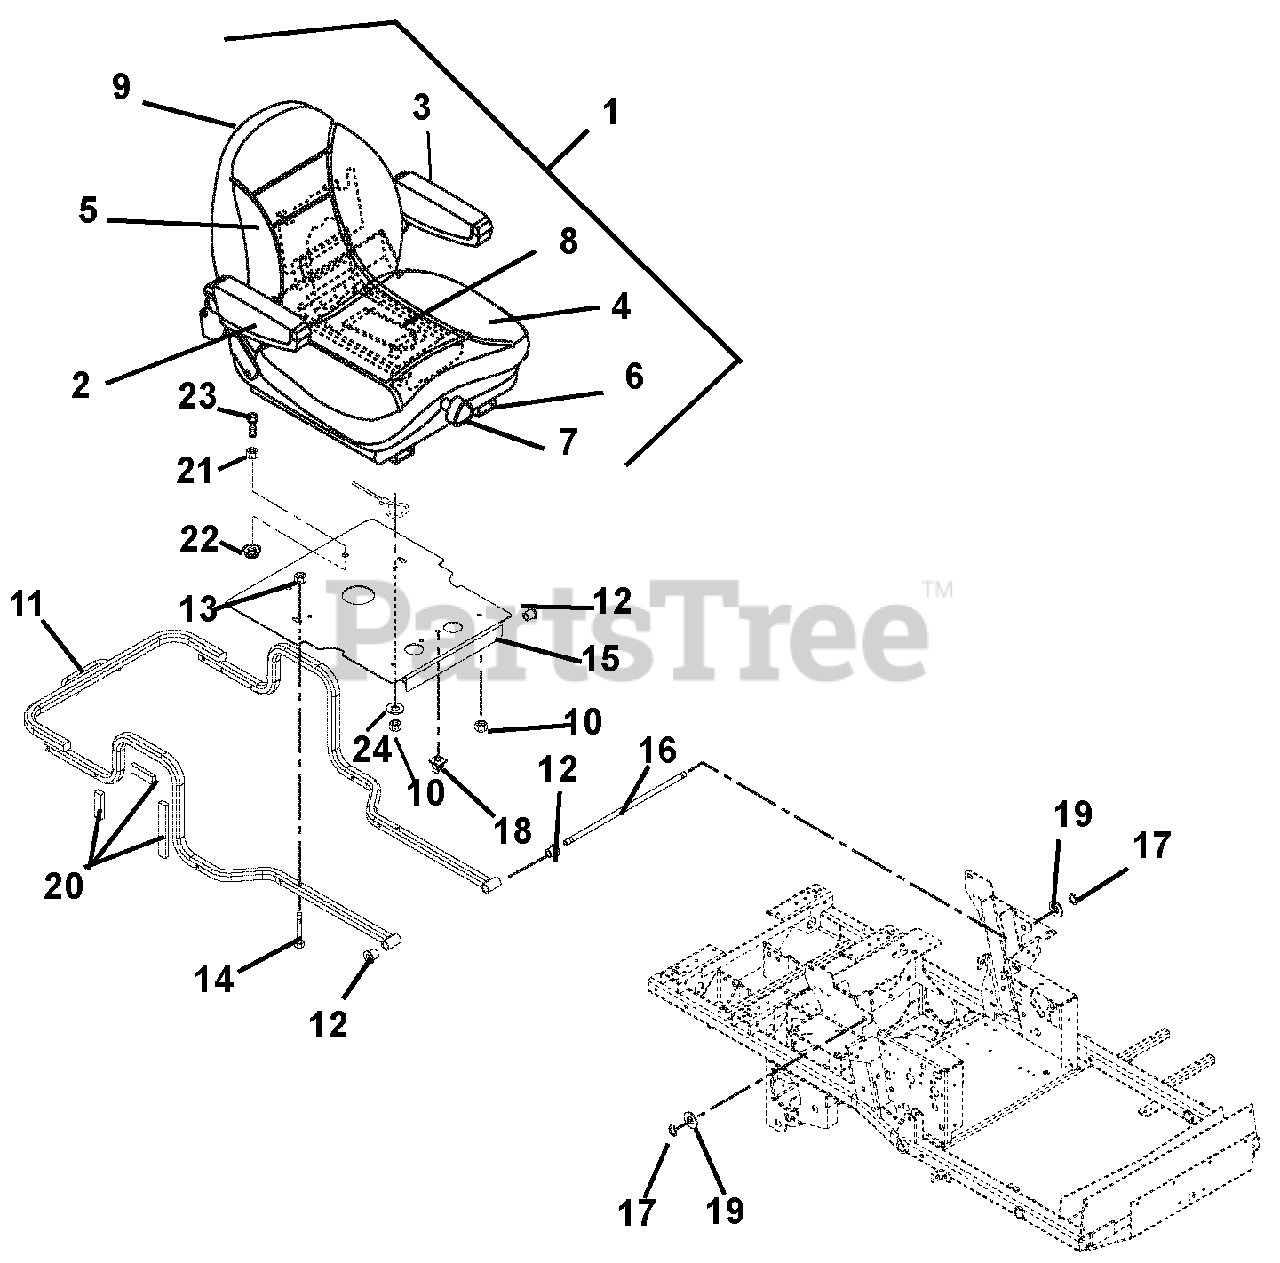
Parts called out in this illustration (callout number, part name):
1	Seat, Suspension, Light Gray
2	Kit, Armrest Assembly - Right Side
3	Kit, Armrest Assembly - Left Side
4	Kit, Seat Cushion, Light Gray
5	Kit, Back Cushion, Light Gray
6	Kit, Seat Slide
7	Kit, Seat Knob
8	Kit, Spring and Saddle
9	Kit, Seat Back Panel
10	Nut, Locking Top Flange .31-18
11	Weldment, Hood Frame
12	Bushing, Flange .515 x .750 x .745 x 1.00
13	Nut, Locking Top Flange .38-16
14	Bolt, Rib Neck .38-16 x 1.50
15	Weldment, Seat Pivot Mount
16	Rod, Seat Frame Pivot
17	Ring, Retaining External .500 x .050
19	Washer, Flat Steel .531 x 1.06 x .095
20	Tape, VHB
21	Nut, Hex .50-13
22	Nut, Locking Top Flange .50-13
23	Bolt, Hex .50-13 x 1.50
24	Washer, Flat Steel .344 x 1.125 x .135
